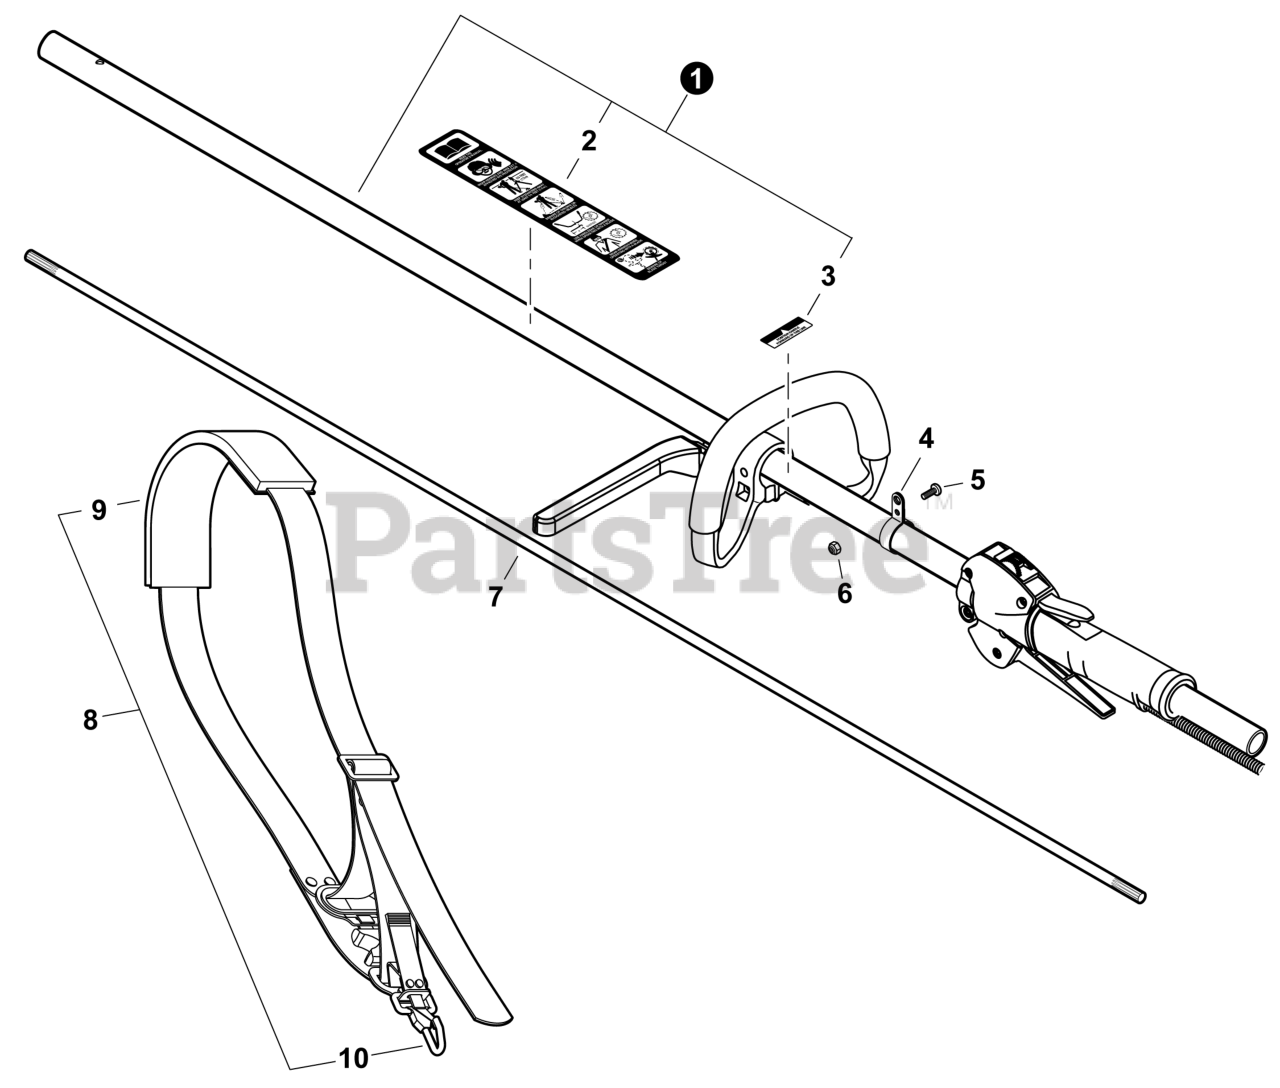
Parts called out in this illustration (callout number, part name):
1	MAIN PIPE ASSY
2	LABEL - CAUTION (BLADE CAPABLE)
3	LABEL - HANDLE
5	BOLT 5×12
7	MAINSHAFT
8	HARNESS ASSY, SHOULDER
9	PAD, SHOULDER
10	HOOK, SNAP
